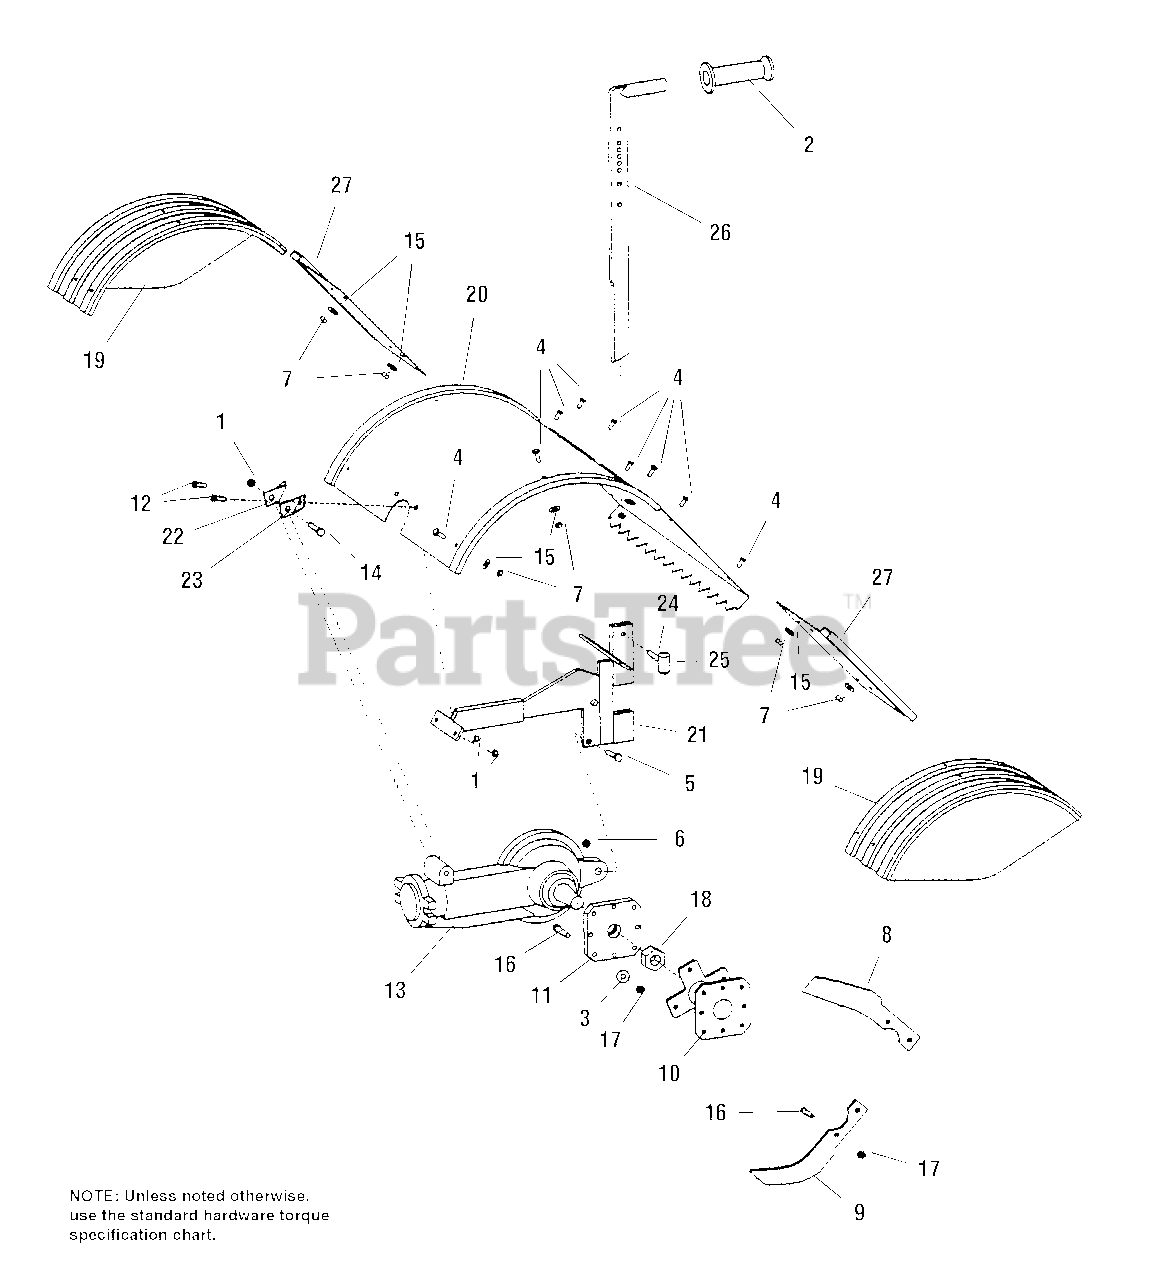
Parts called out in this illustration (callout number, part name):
1	NUT-Bi-Way Lock, 5/16-18
2	HANDLE GRIP, Black
3	LOCKWASHER-Spring, 5/16"
4	BOLT-Hex Hd, 1/4-20 x 1/2"
5	BOLT-Hex Hd, 3/8-16 x 1-3/4"
6	LOCKNUT-Hex, 3/8-16
7	NUT-Keps, 1/4-20
8	TINE-Bolo, Right Side
9	TINE-Bolo, Left Side
10	HOLDER-Bolo Tine, Both Sides
12	BOLT-HHCS, 5/16-18 x 3", Grade 5
13	TILLER DRIVE TRANSMISSION
14	BOLT-Hex Hd, 5/16-18 x 3"
15	WASHER-Flat, 1/4"
16	BOLT, 8mm x 30mm
17	NUT, 8mm x 1.25mm
18	NUT, 200mm x 1.50mm
19	SIDE SHIELD-Hood, Both Sides
20	HOOD-Tiller
21	BRACKET-Depth Regulator
22	BRACKET-Hood, Right Side
23	BRACKET-Hood, Left Side
24	DETENT PIN, 5/16-18 x 1", Drag Stake
25	KNOB-T-Handle, Drag Stake
26	LEVER-Drag Stake
27	EXTENSION-Hood Flap, Both Sides
